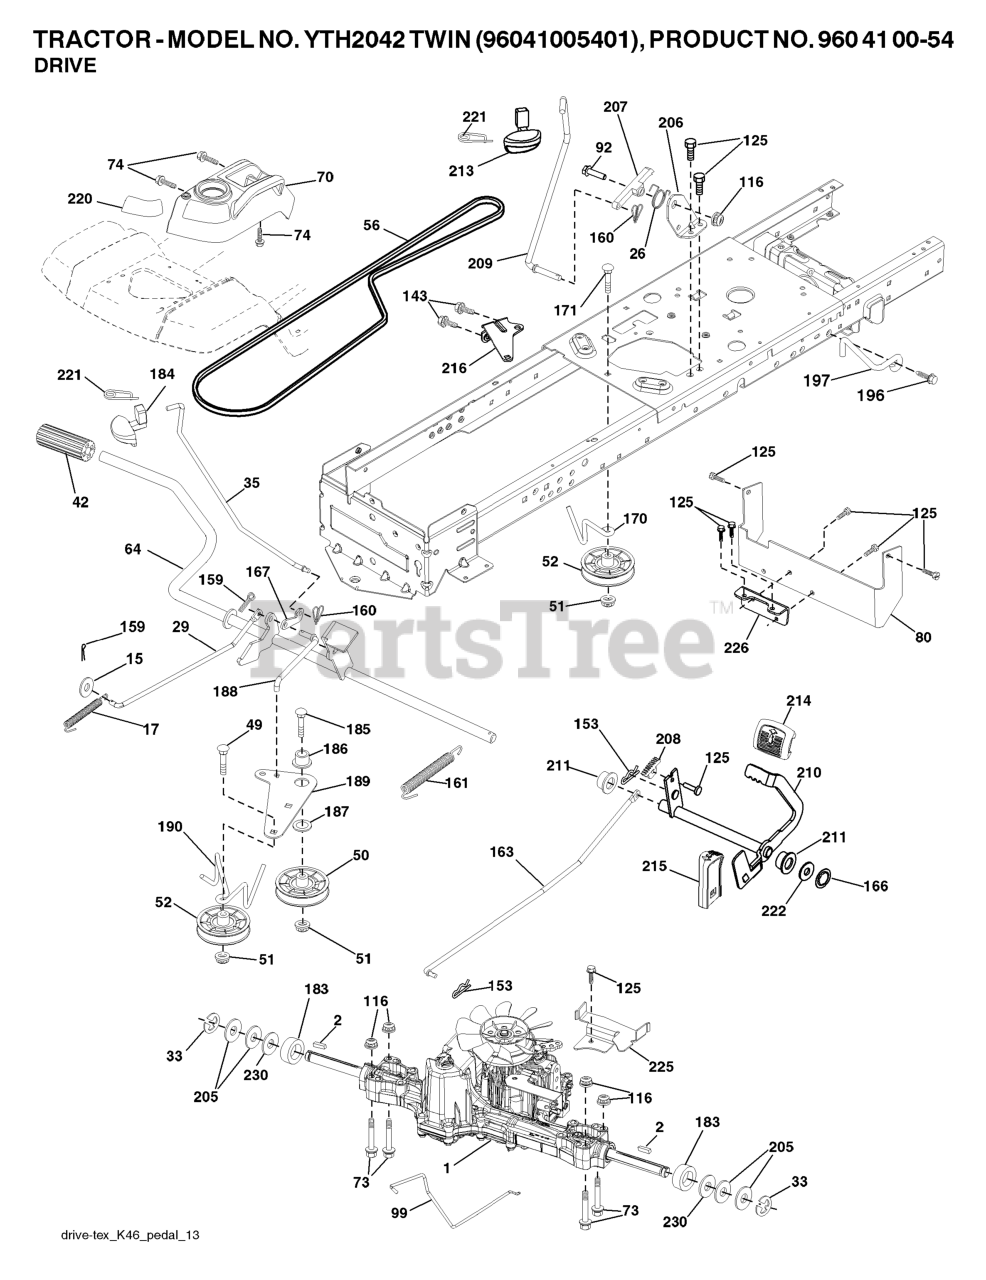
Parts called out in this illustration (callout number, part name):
2	SQUARE KEY
15	WASHER
17	SPRING.BRAKE.K46.GREEN
26	SPRING.RETURN.CRUISE
29	ROD.BRAKE.K46
35	ROD.BRAKE.PARKING.GT.H
42	PEDAL COVER T
50	IDLER.FLAT.910.OFFSET
51	NUT LOCK FLG 3/8-16 UNC
52	IDLER.V-GROOVE.910.OFFSET
56	V-BELT.MOWER.92.40.42/K46
64	SHAFT.ASM.PEDAL.BRK.CNTR
70	RP CONSOLE.ASM.PCH.W/TB
73	BOLT HEX 5/16-18 GR 5
74	SCREW.HI-LO.CONSOLE
80	STRAP TORQUE
92	BOLT
99	ROD.SPRING.BYPASS.K46.LT.Z
116	NUT LOCK HEX FLANGE 5/16-18
125	SCREW
143	Screw 5/16-18 x 1/2 Hex, Self Tapping 5/16-18 x 1/2
153	RETAINER M
159	COTTER PIN
160	RETAINER CLIP
161	SPRING, RETURN LT
163	ROD.CONTROL.PEDAL.K46
166	NUT.PUSH.625.2006
167	LATCH.BRAKE.SPRING
170	KEEPER.V-IDLER.CENTER.
183	SPACER AXLE
184	HANDLE.PARKG.BRK.HUSQ X667
186	SPACER.RETAINER
187	WASHER 12/32X2X10GA
188	RP.LINK.CLUTCH.GROUND.DRIVE
189	BELLCRANK.GROUND.DRIVE.TEX.
190	KEEPER.BELLCRANK.DRIVE
196	SCREW 3/8-16X1
197	LINK.CLUTCH.ANIT-ROTAT
206	BRKT.MOUNT.LATCH.CRUIS
207	LATCH.CONTROL.CRUISE
208	GEAR.SECTOR.CONTROL.CR
209	ROD.CONTROL.CRUISE.GT.
210	ROCKER.ASM.PEDAL.CONTR
211	BEARING.NYLON
213	KNOB.CONTROL.CRUSIE.HU
214	PEDAL.FORWARD.TEX.GT.4
215	PEDAL.REVERSE.TEX.GT.4
216	BRACKET.PULLEY.IDLER.W/TEX
220	REFLECTOR.RH.TEX GT
221	RETAINER.SPRING.CLIP.H
222	WASHER 21/32 X 1-1/4 X 10 GA.
225	KEEPER.BELT.TRANSAXLE.K46
226	BRACKET.MOUNT.TORQUE.K46.TLT
230	WASHER.HARDENED
